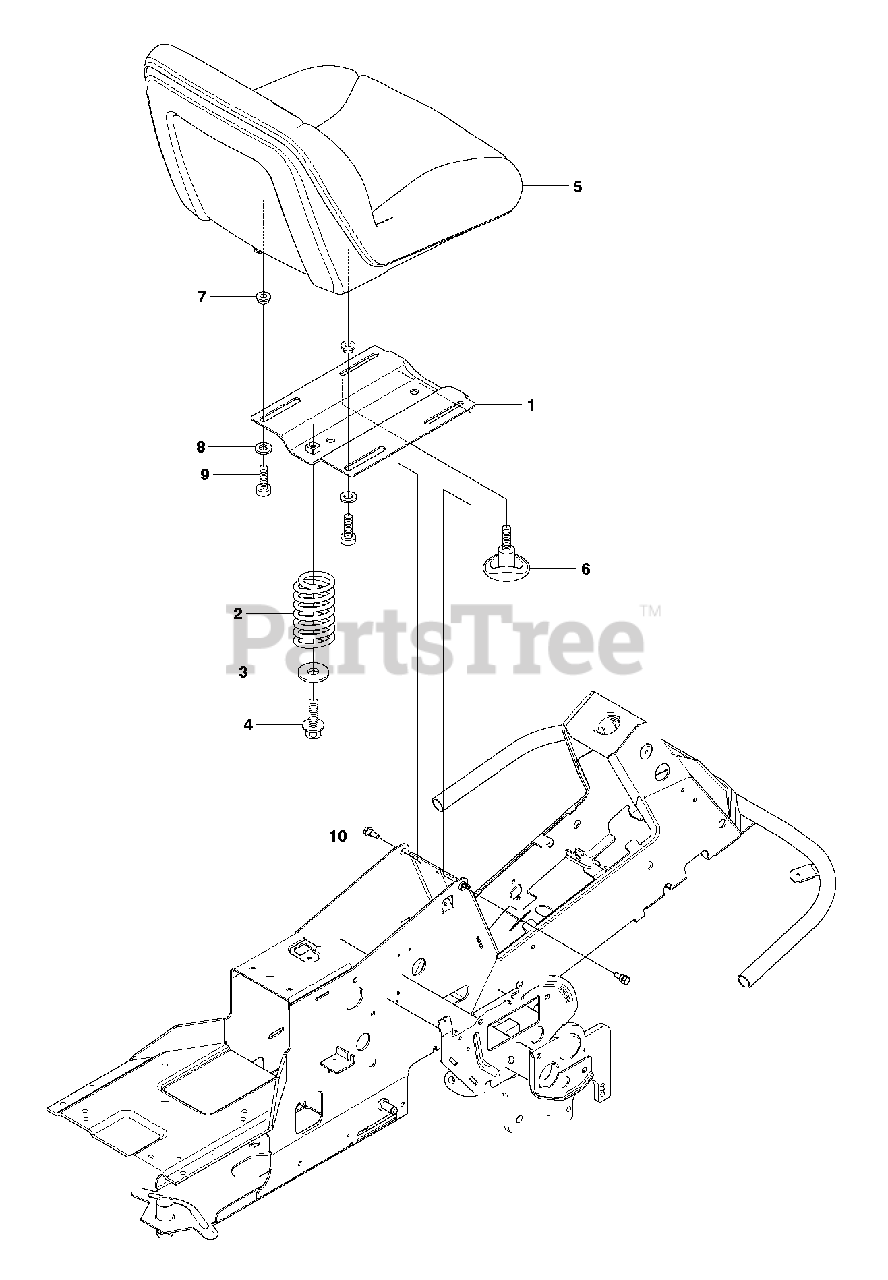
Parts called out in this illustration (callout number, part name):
2	SEAT SPRING
4	SCREW M10X25
6	ADJUSTING KNOB
